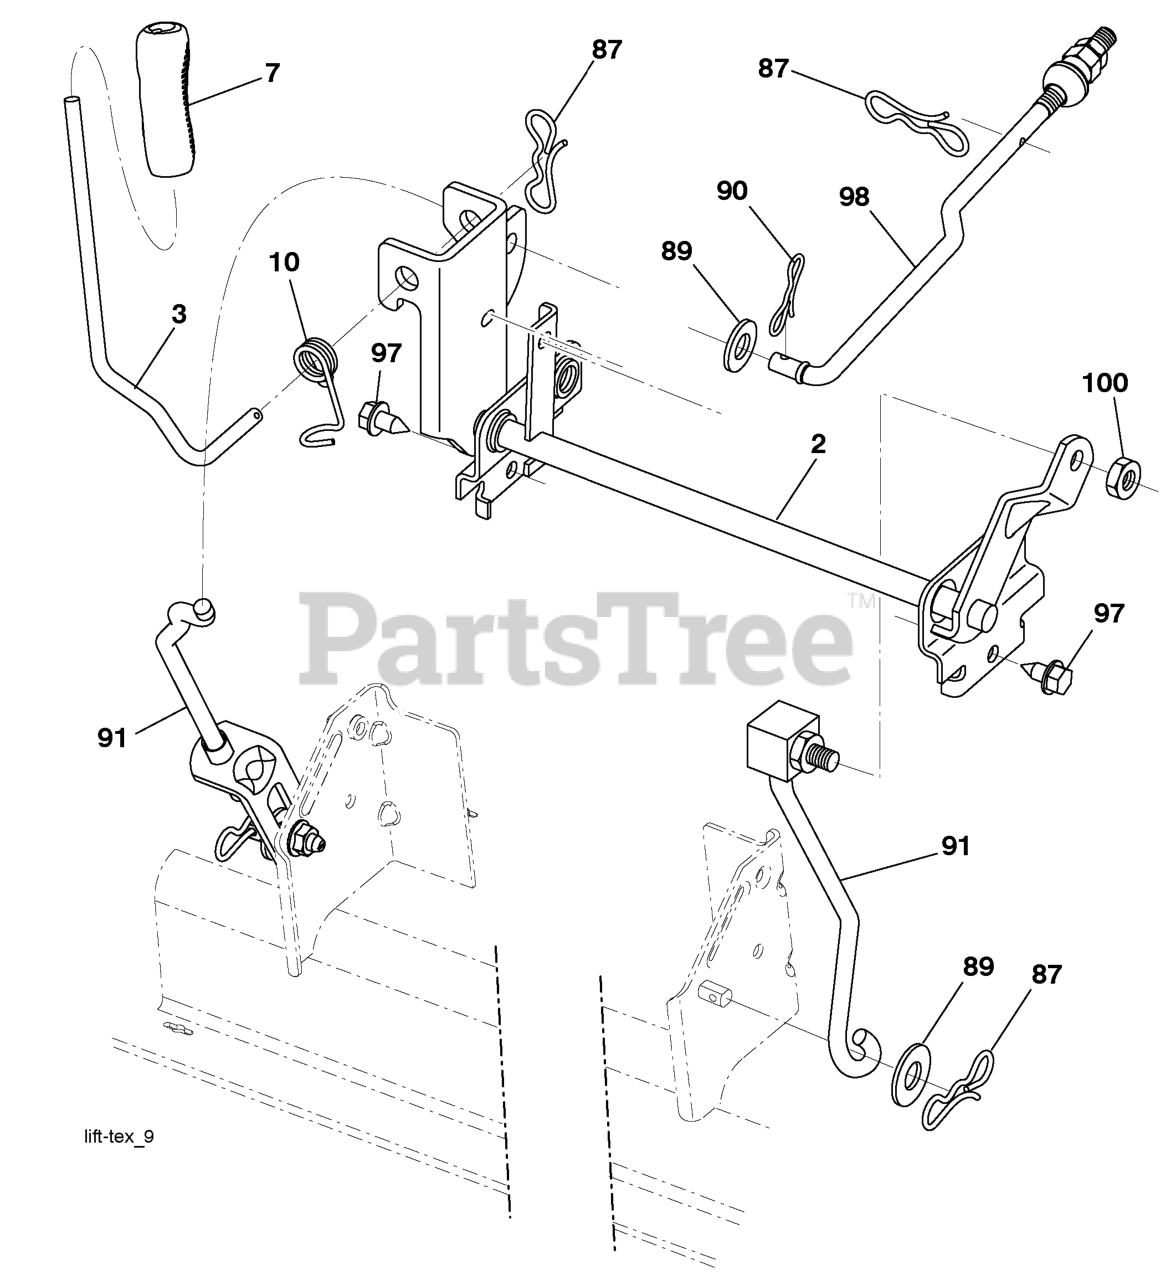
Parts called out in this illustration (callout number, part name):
2	SHAFT.ASM.CROSS.LIFT
3	LEVER.LIFT.HANDLE.LT
7	GRIP.HANDLE.LIFT.PVC.BLACK
10	SPRING.TORSION.LIFT.HANDLE
87	PIN.COTTER.7/16.BOW TI.
89	WASHER.CLEAR.ZINC
90	PIN.COTTER.5/16.BOW TI
91	LINK.ASM.LIFT.REAR
97	SCREW, 3/8-16X3/4
98	LINK.ASM.SUSP.FRONT.MW
100	LOCKNUT
101	LINK.ASM.LIFT.FIXE.38/42/46"
